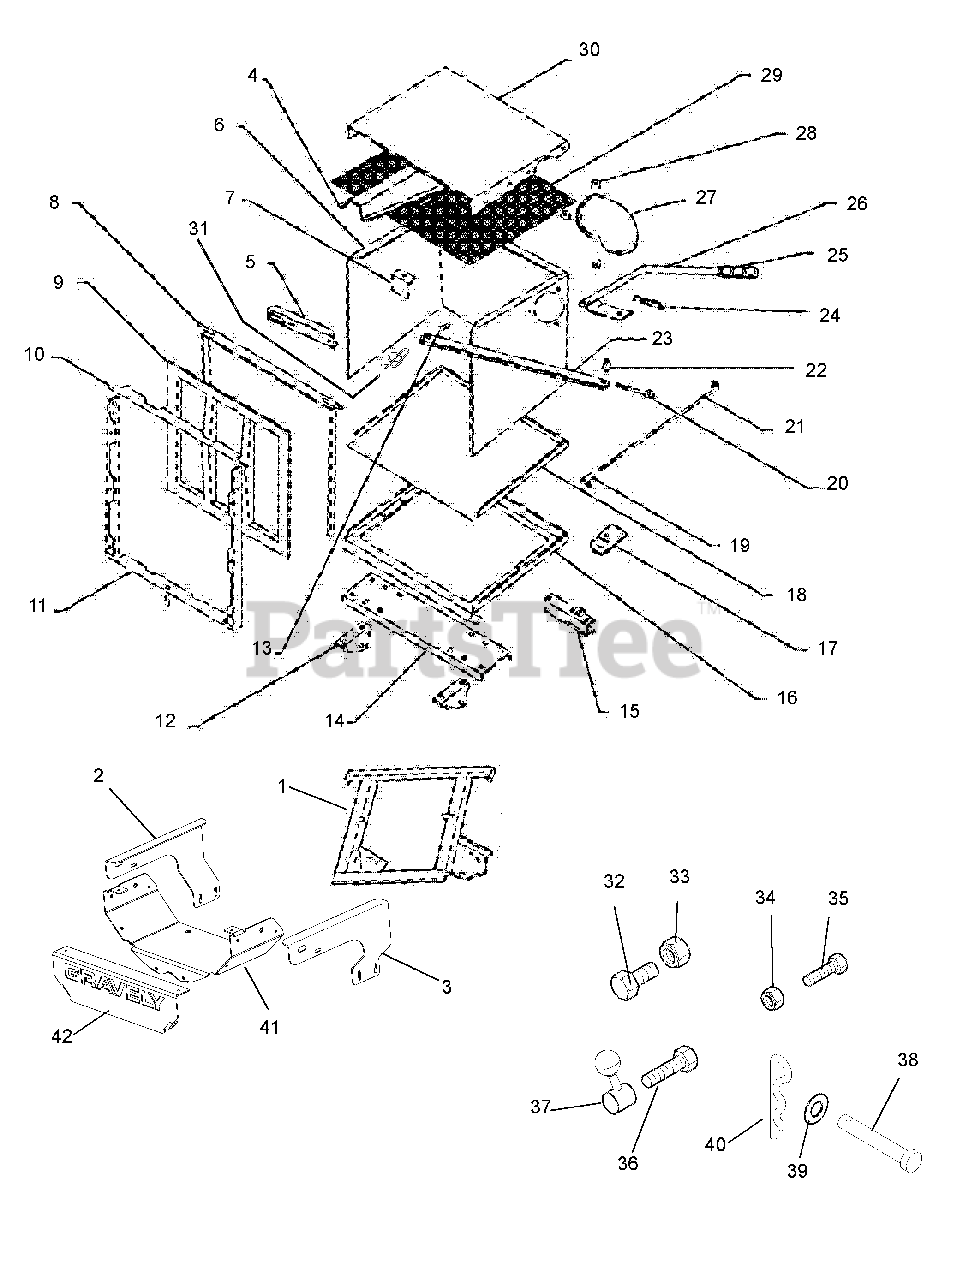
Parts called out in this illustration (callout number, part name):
1	Frame, Top Main
2	Bracket, Left
3	Bracket, Right
4	Screen Support
5	Handle Mount
6	Box Back and Sides
7	Fill Gauge
8	Box Door/Frame
9	Plastic Door
10	Upper Door Member
11	Door Frame Assembly
12	Pivot Bracket
13	Linkage Pin
14	Base Frame Pivot Mount
15	Latch Hook Plate
16	Base Frame
17	Latch Hook
18	Box Bottom
19	Ball Joint
20	Adjusting Screw
21	Latch Rod
22	Nut, Adjusting
23	Rod, Linkage
24	Spring, Latch
25	Grip, Handle
26	Handle, Box
28	Clamp, Inlet
30	Box Top, Aluminum
31	Pin, Rue-Lock
32	Bolt, Hex .75-10 x 1.50 Grade
33	Nut, Lock .75-10
34	Nut, Nylon Lock .375-16
35	Bolt, Hex .375-16 x 3.0 Grade 5
36	Bolt, Hex .50-13 x 1 Grade 5
37	Handle, Pivot Frame
38	Pin, Detent .625 x 3.00
39	Washer, Flat Steel .656 x 1.31 .095
40	Pin, Hair .156 x 2.625
41	Bracket, Main
42	Bracket, Center
